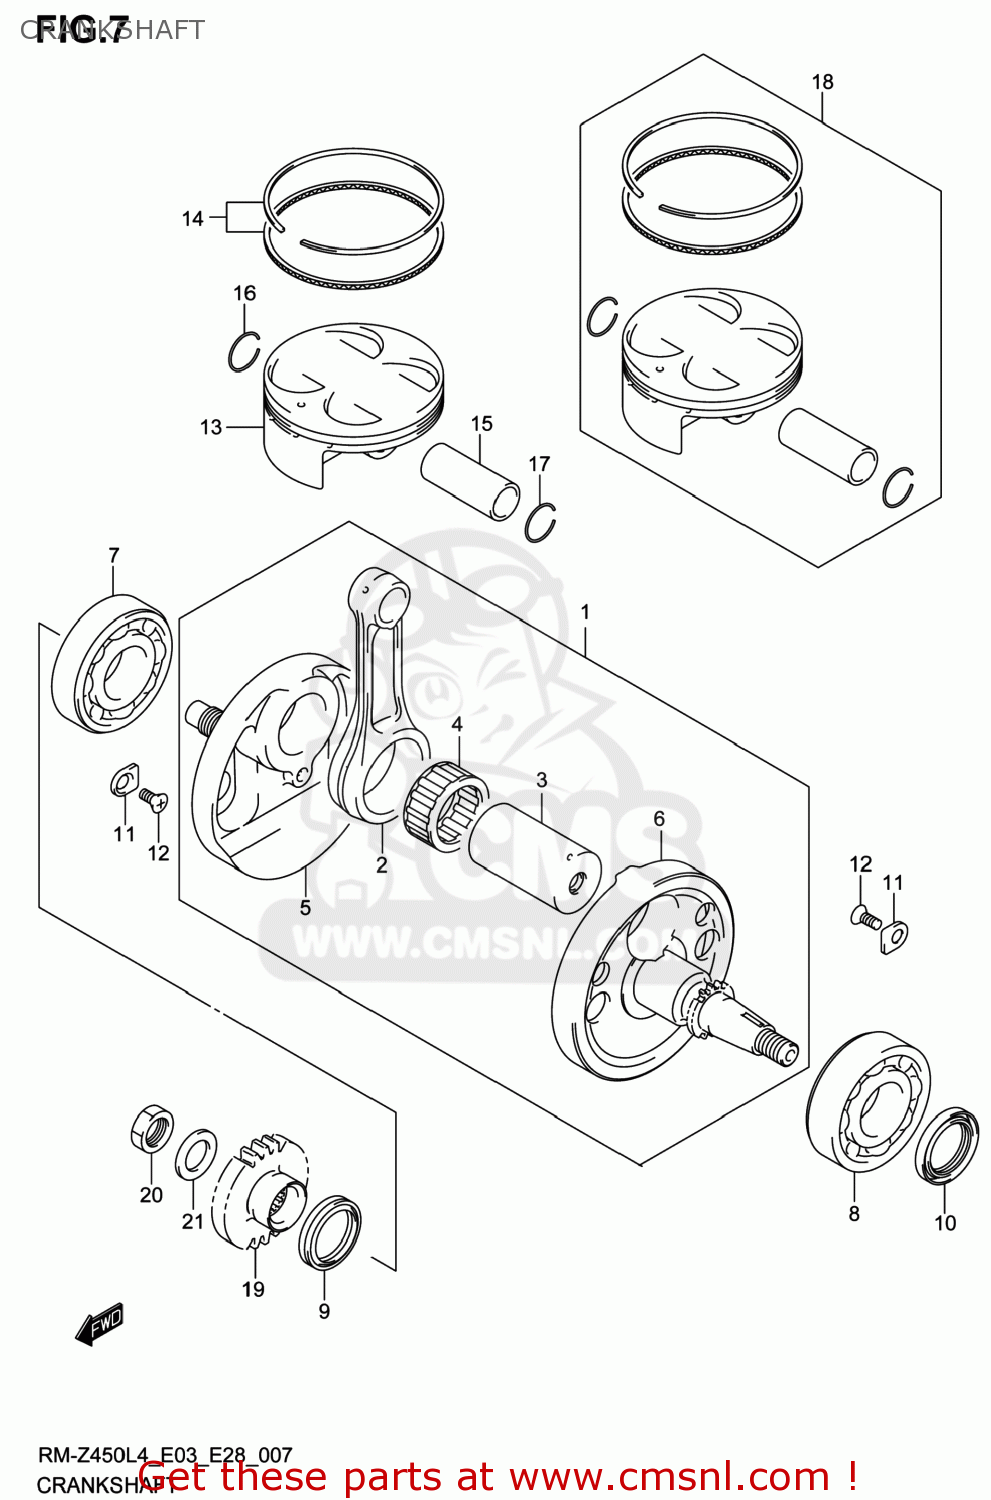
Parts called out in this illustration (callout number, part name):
1	CRANKSHAFT ASSY
2	CONNECTING ROD
3	PIN,CRANK
4	BEARING(34X42X20)
5	CRANKSHAFT,R
6	CRANKSHAFT,L
7	BEARING(30X72X19)
8	BEARING(32X75X20)
9	SEAL,OIL(30X40X7)
10	SEAL,OIL(32X47X6)
11	RETAINER,COUNTER BEARING,R
12	SCREW(6X12)
13	PISTON
14	RING SET,PISTON
15	PIN,PISTON
16	RING,SNAP
17	CIRCLIP
18	PISTON KIT
19	GEAR,PRIMARY DRIVE
20	NUT
21	WASHER
